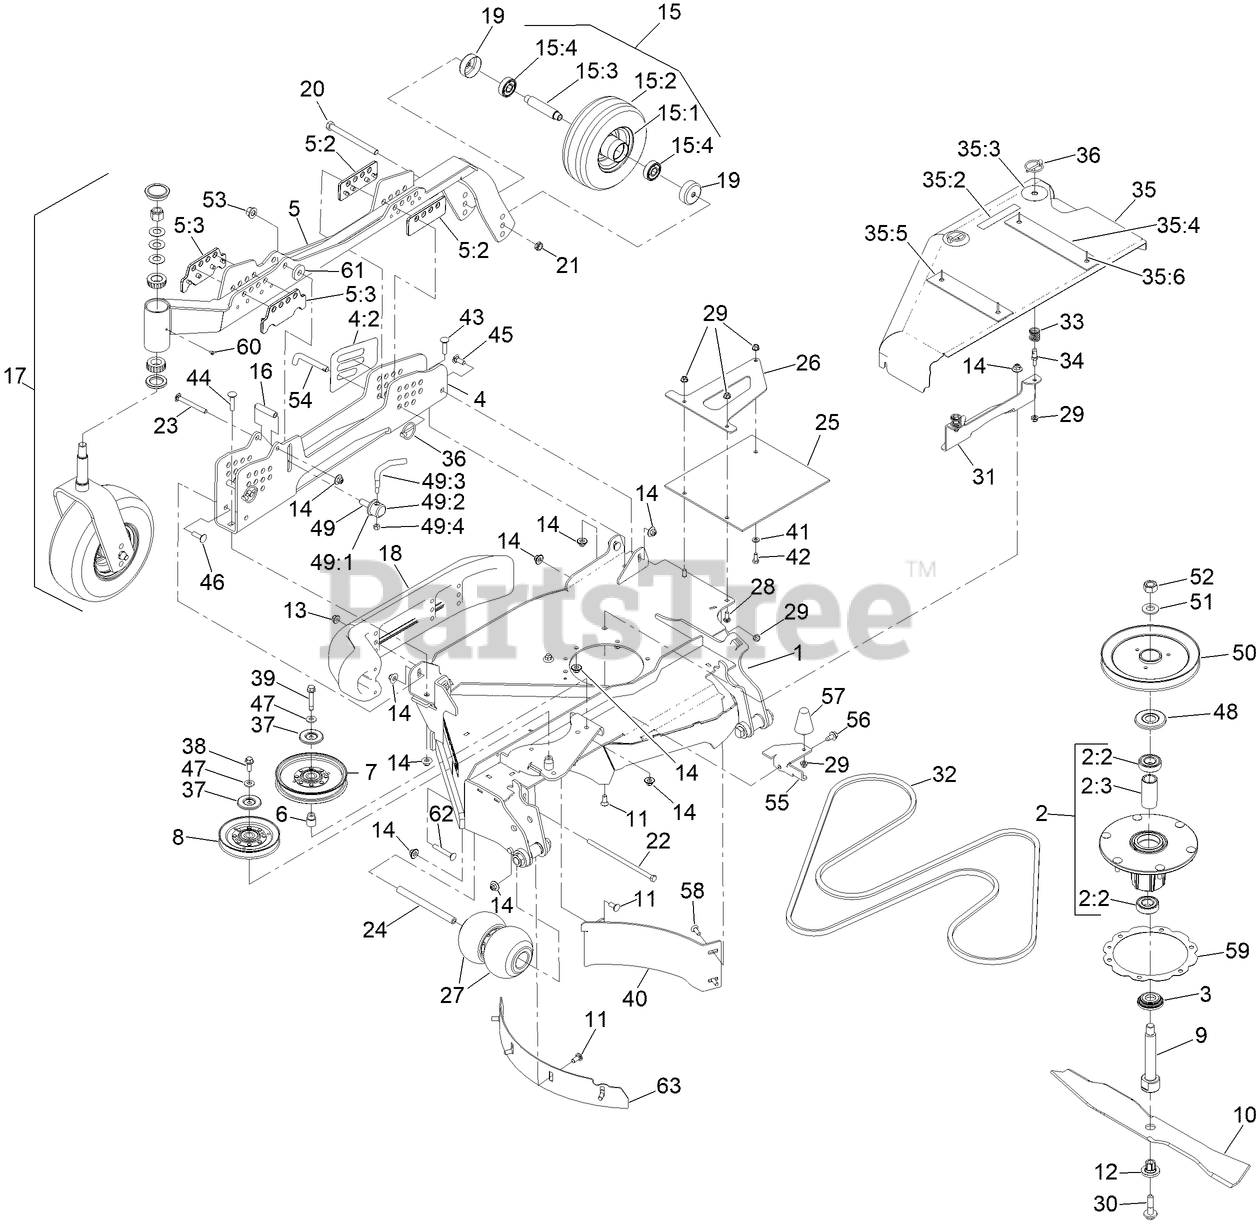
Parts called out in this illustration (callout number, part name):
1	ASM-DECK, RH WING [W/DECALS]
2	SPINDLE ASM
2:2	BEARING-BALL
2:3	SPACER-BEARING
3	GUARD-BOTTOM
4	ASM-CHANNEL, HOC RH W/DECALS
4:2	DECAL-HEIGHT OF CUT, RH
5	ASM-RH GAUGE WHEEL ARM
5:2	PLATE-GUIDE, REAR
5:3	PLATE-GUIDE, FRONT
6	BUSHING-IDLER
7	IDLER-PULLEY
8	IDLER-V
9	SHAFT-SPINDLE
10	BLADE-24.50 MULCH
11	BOLT-CARR
12	BUSHING-HEX
13	NUT-HF, NI
14	NUT-FLANGE, NI
15	WHEEL AND TIRE ASM
15:1	WHEEL
15:3	AXLE-CASTER
15:4	BEARING
16	SPACER
17	CASTER WHEEL ASM
18	SKID-BUMPER, DECK
19	GUARD, SEAL
20	SCREW-HH
21	NUT-HEX
22	SCREW-HH
23	SCREW-CARR
24	SPACER-WHEEL
25	GUARD-TIRE
26	SUPPORT-FLAP, RH
27	ROLLER-SCALP, ANTI
28	SCREW-CARR
29	NUT-HF, NI
30	SCREW-SEMS
31	BRACKET-SHIELD MOUNT, OUTER
32	BELT-V
33	SPRING
34	PIN, SPRING
35	RH WING SHIELD ASM
35:2	DECAL-NO STEP
35:3	DECAL-SCRATCH COVER
35:5	PLATE-FRONT
35:6	RIVET-POP
36	PIN-LYNCH
37	SHIELD-DUST
38	SCREW-HHF
39	SCREW-HHF W/ PATCH
40	BAFFLE-BLOCK, RH WING
41	WASHER-PLAIN
42	SCREW-HH
43	SCREW-CARR
44	SCREW-CARR
45	BOLT-CARR
46	BOLT-CARR
47	WASHER-BELLEVILLE
48	GUARD-BEARING, TOP
49	LEVER ASM
49:1	SCREW-LOCK
49:2	CAP-LOCK
49:4	NUT-LOCK, NI
50	SHEAVE-DRIVE, BLADE
51	WASHER
52	NUT-HEX
53	NUT-LOCK
54	PIN-HOC
55	BRACKET-COVER RETAINER
56	SCREW-HWH
57	BUMPER-RUBBER
58	SCREW-CARR
59	RING-SPACER, HOUSING
61	WASHER
62	SCREW-CARR
63	BAFFLE-DEPTH, RH
